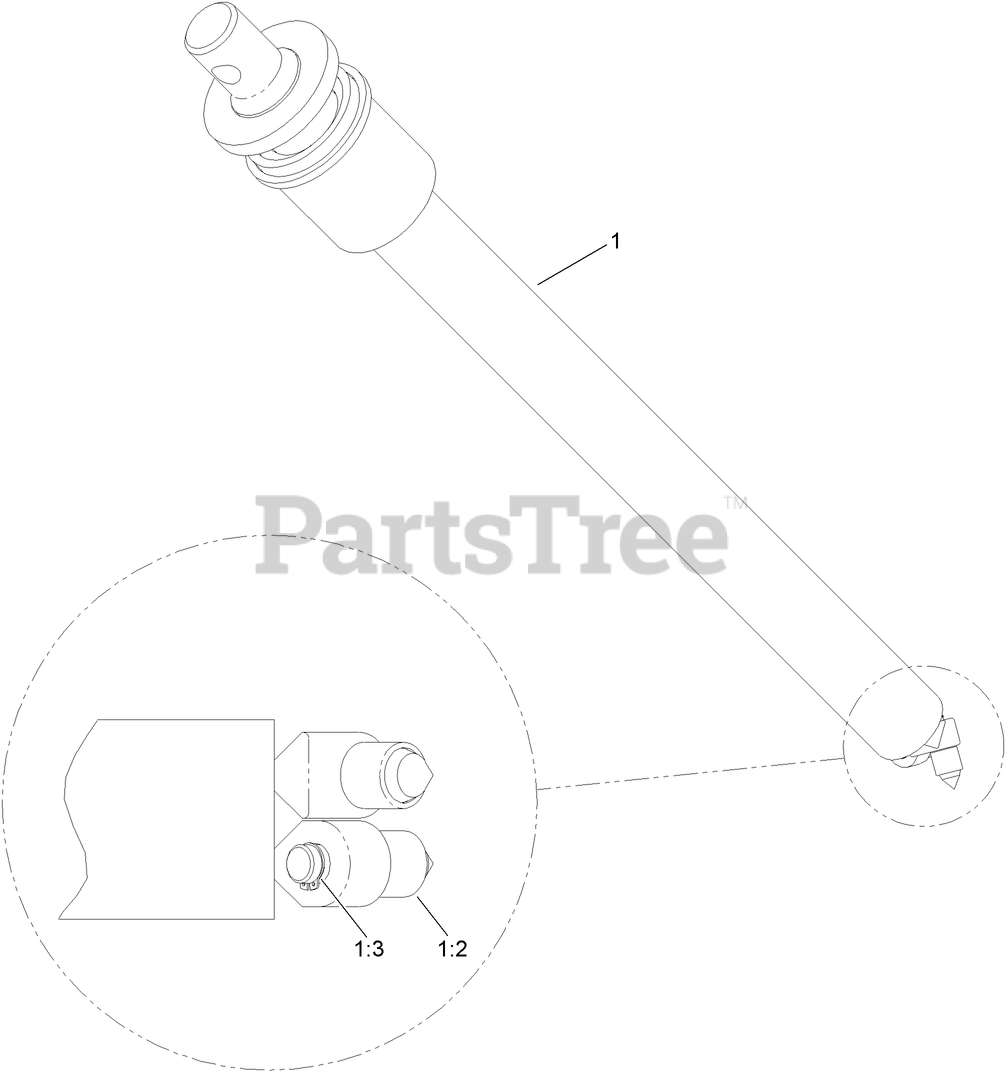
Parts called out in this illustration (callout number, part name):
1	STAKE-ROCK
1:2	BIT-BULLET, MINI
1:3	RING-SNAP
